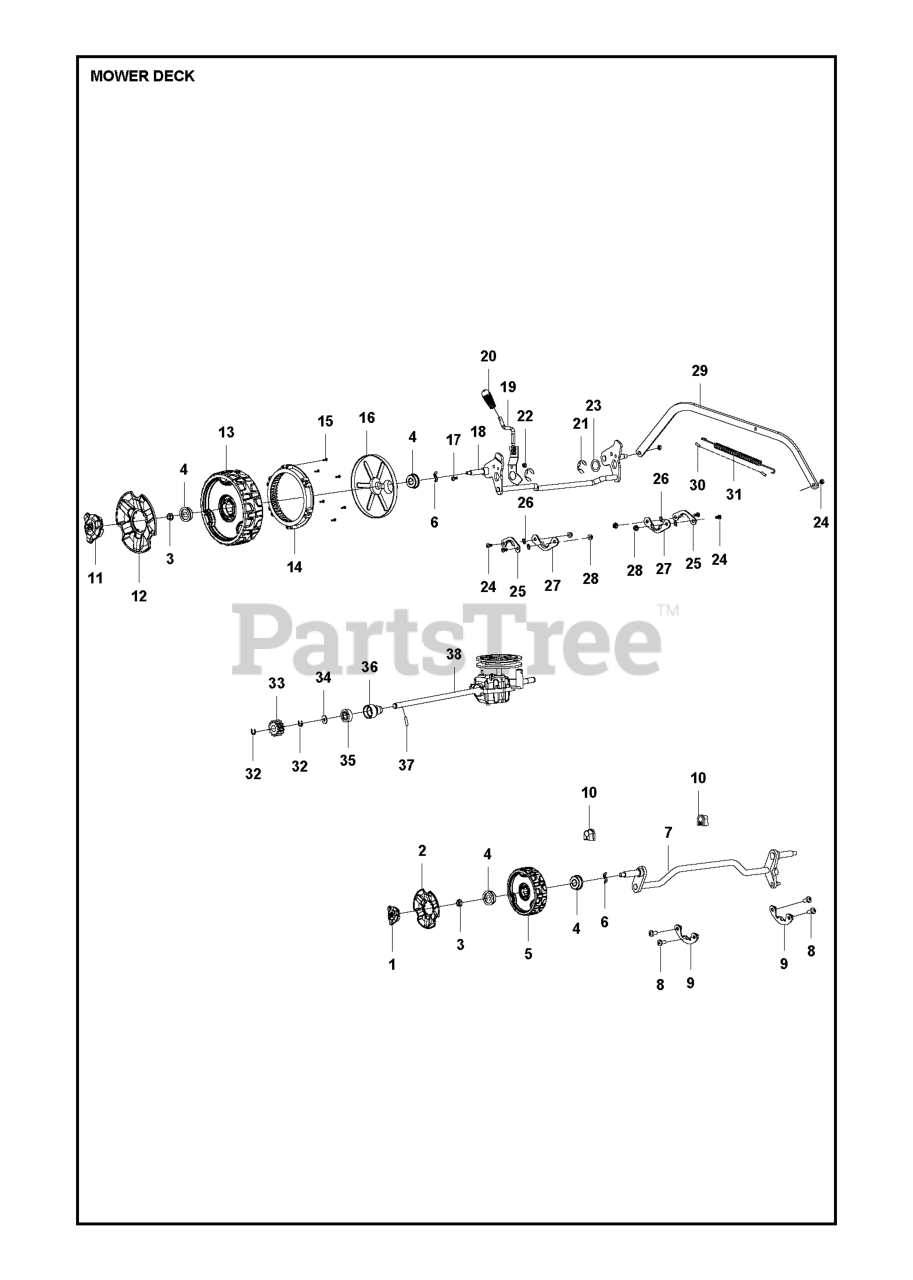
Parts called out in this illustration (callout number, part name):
1	WHEEL COVER 6" #25340700101
3	LOCKING BOLT M8,GB6187.1 #2680
6	WASHER Ï?12 #26800706202
11	WHEEL COVER 8" #25341000101
12	WHEEL COVER 8" #25341100101
13	WHEEL 8" #25341200101
14	GEAR WHEEL #25229900201
16	COVER #25342800101
17	WASHER M6*14 #26800203001
20	KNOB HEIGHT ADJUSTMENT #25341
21	WASHER Ï?19*1.5,GB896 #2680090
22	LOCKING BOLT M6,GB889.1 #26800
23	WASHER #26300107601
24	SCREW M6*16 #26800204601
26	O-RING #25100175201
27	FIXING PLATE #26300124401
28	LOCK NUT M6,GB/T6187.1-2000 #2
30	TUBING #29000300101
31	SPRING #26801103903
32	WASHER Ï?9,GB896 #26800900201
34	WASHER Ï?12.8*Ï?20*0.8 #268007
36	BEARING HOUSING #26900211501
